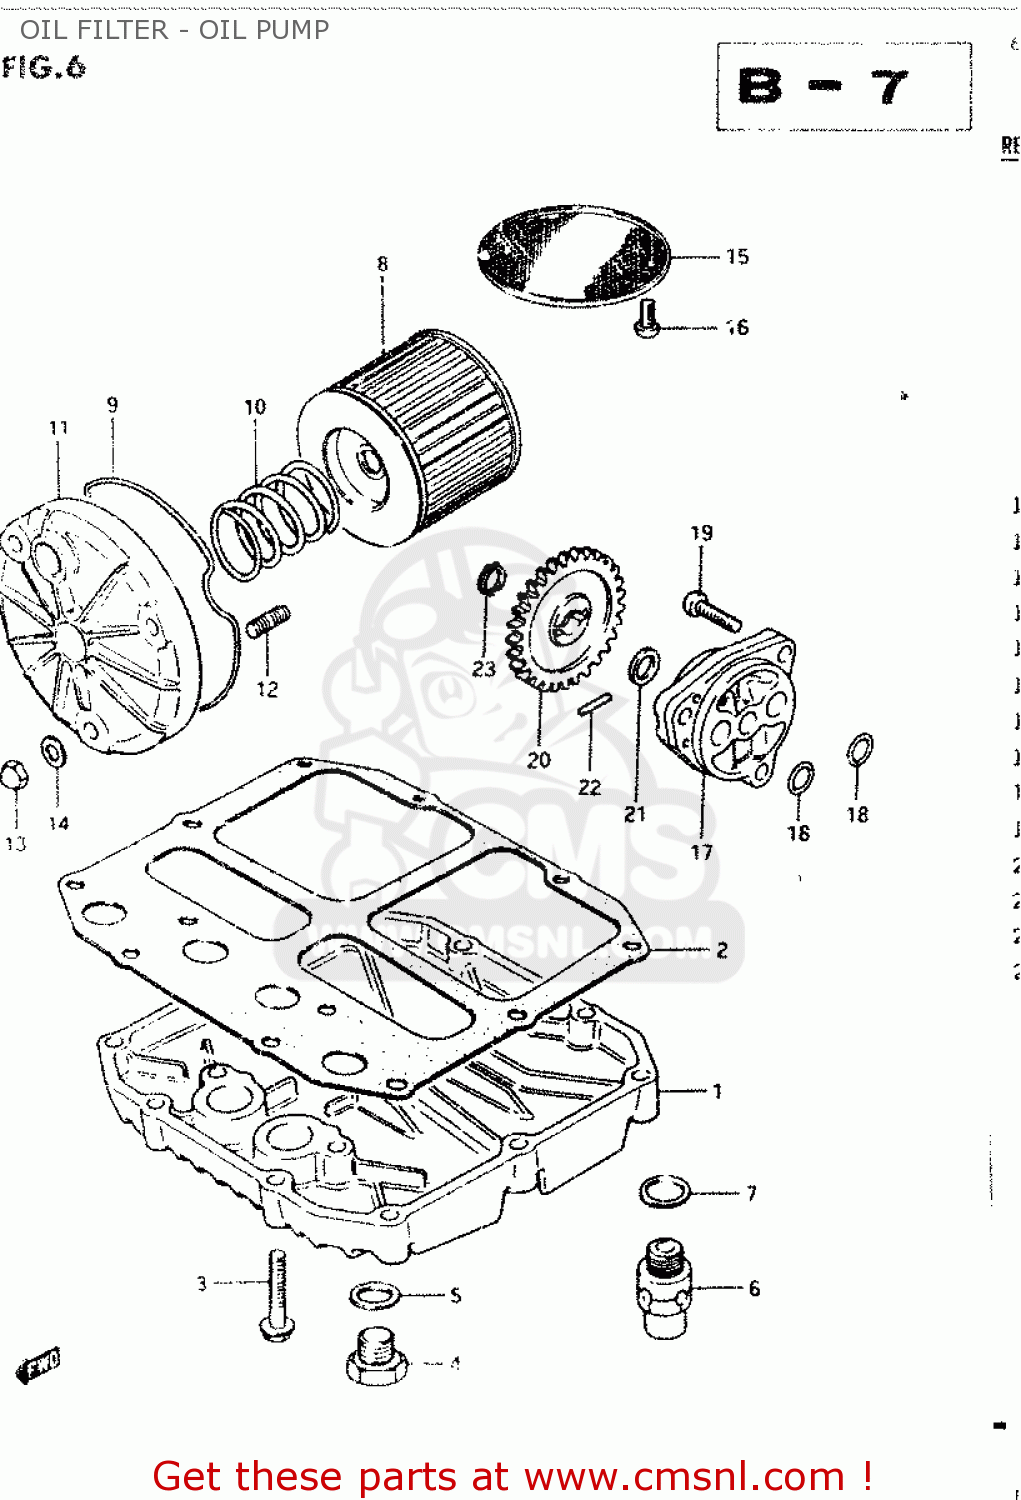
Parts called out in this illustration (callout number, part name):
1	PAN,OIL
2	GASKET,OIL PAN (MCA)
3	BOLT 6X30
4	PLUG
5	GASKET(14X19.2X2) (NAS)
6	VALVE ASSEMBLY,OIL RELIEF
7	WASHER
8	FILTER ASSY,ENGINE OIL
9	O RING,OIL FILTER CHAMBER CAP
10	SPRING
11	CAP,OIL FILTER
12	STUD 6X20
13	NUT 6MM
14	WASHER
15	STRAINER,ENGINE OIL
16	SCREW 6X12
17	PUMP ASSY,ENGINE OIL
18	O RING(D:1.9,ID:13)
19	SCREW
20	GEAR,OIL PUMP DRIVEN
21	SHIM
22	PIN(4X15.8)
23	CIRCLIP
